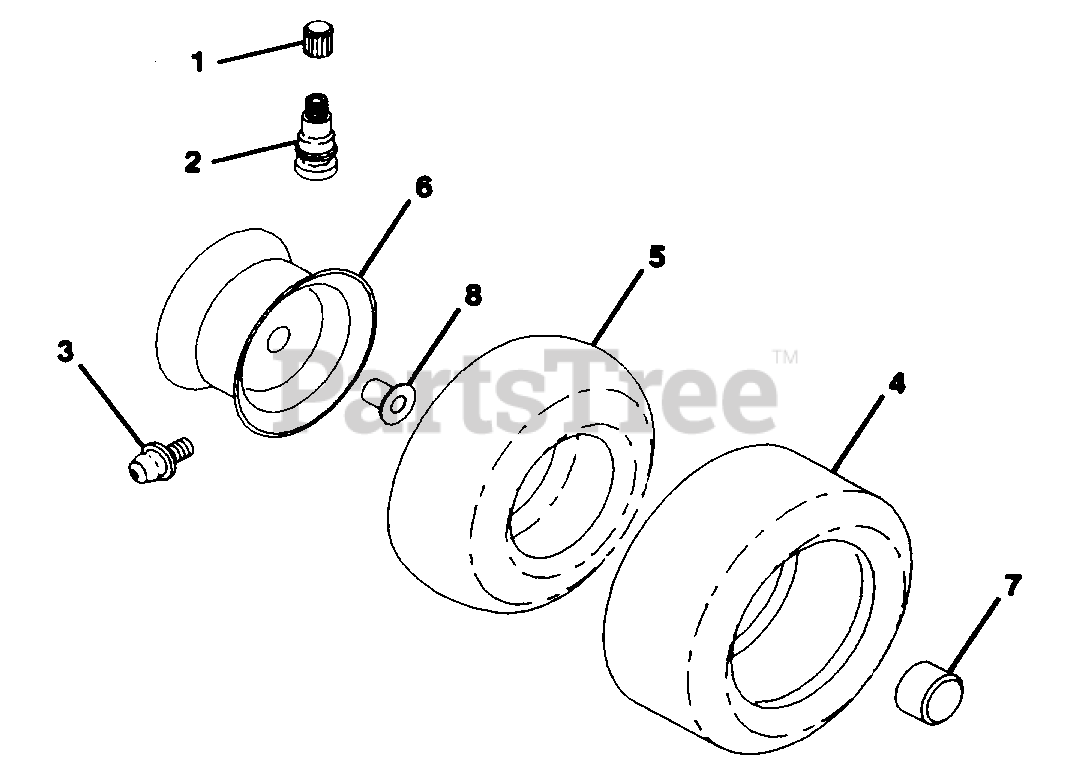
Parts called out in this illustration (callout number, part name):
1	Cap Valve Tire (AYP part number)
2	Stem Valve (AYP part number)
3	Fitting Grease (Front Wheel Only) (AYP part number)
4	Tire, FTs 15x60-6 Service (AYP part number)
4	Tire R Ts 18x8 5-8 S Service (AYP part number)
5	Tube,Front (Optional Service Item Only)
5	Tube,Rear (Optional Service Item Only) (AYP part number)
6	Rim Assembly 6" Front (AYP part number)
6	Rim Assembly 8" Rear (AYP part number)
7	Cap Axle Blk 1 50 X 1 00 (AYP part number)
8	Bearing (AYP part number)
